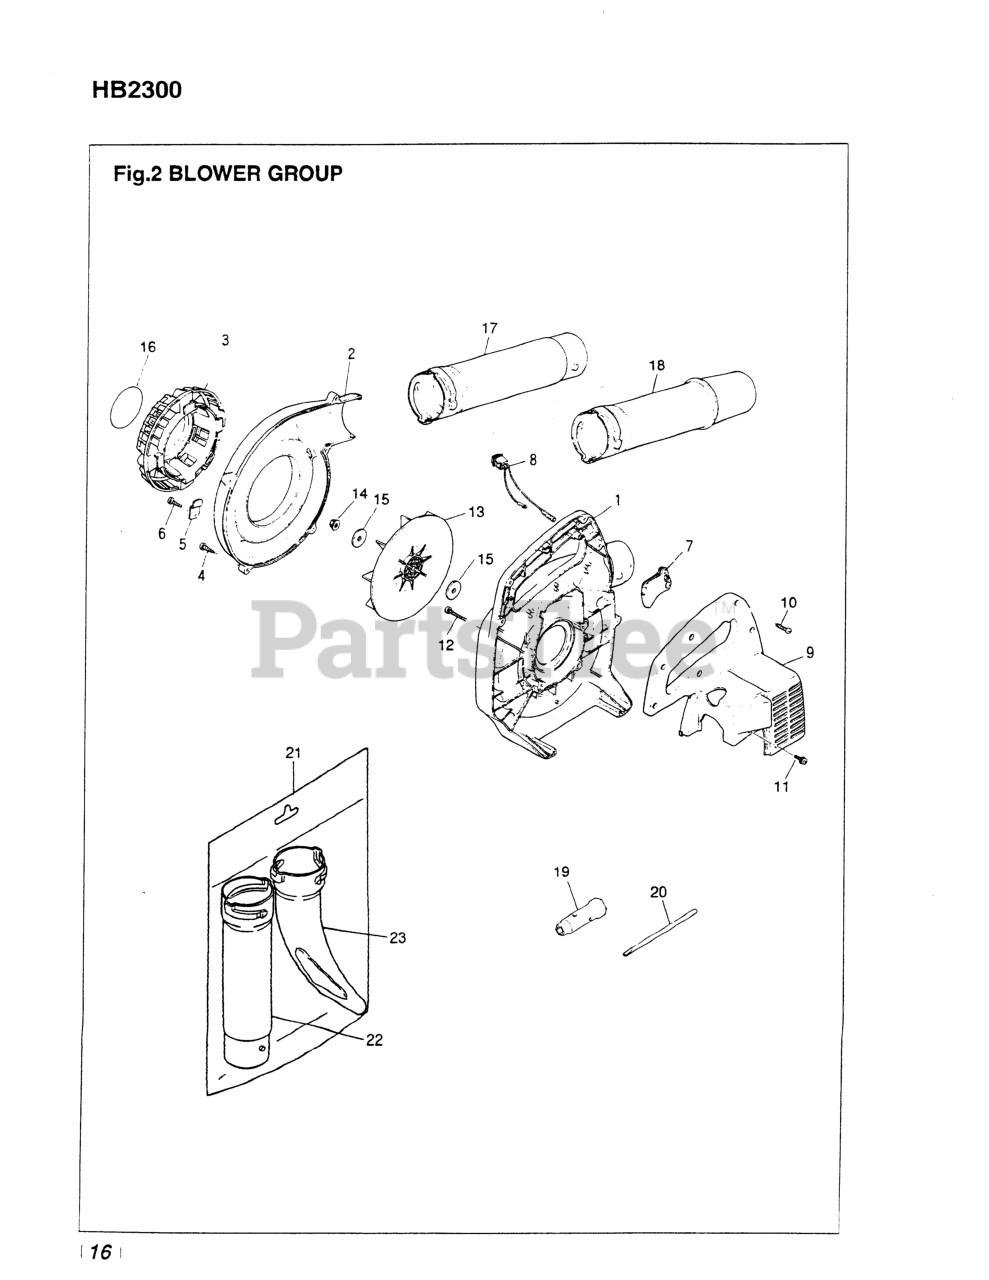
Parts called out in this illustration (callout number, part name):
1	848-L0F-55A1
2	COVER, VOLUTE
3	GUARD
4	SCREW
6	SCREW
7	LEVER
8	SWITCH
9	COVER
10	SCREW
11	SCREW, M5 x 12
12	SCREW, M5 x 35
13	FAN
15	WASHER
16	LABEL
18	PIPE, END
19	SOCKET, HEX, 3/4
21	FLAT NOZZLE SET
23	NOZZLE, FLAT
